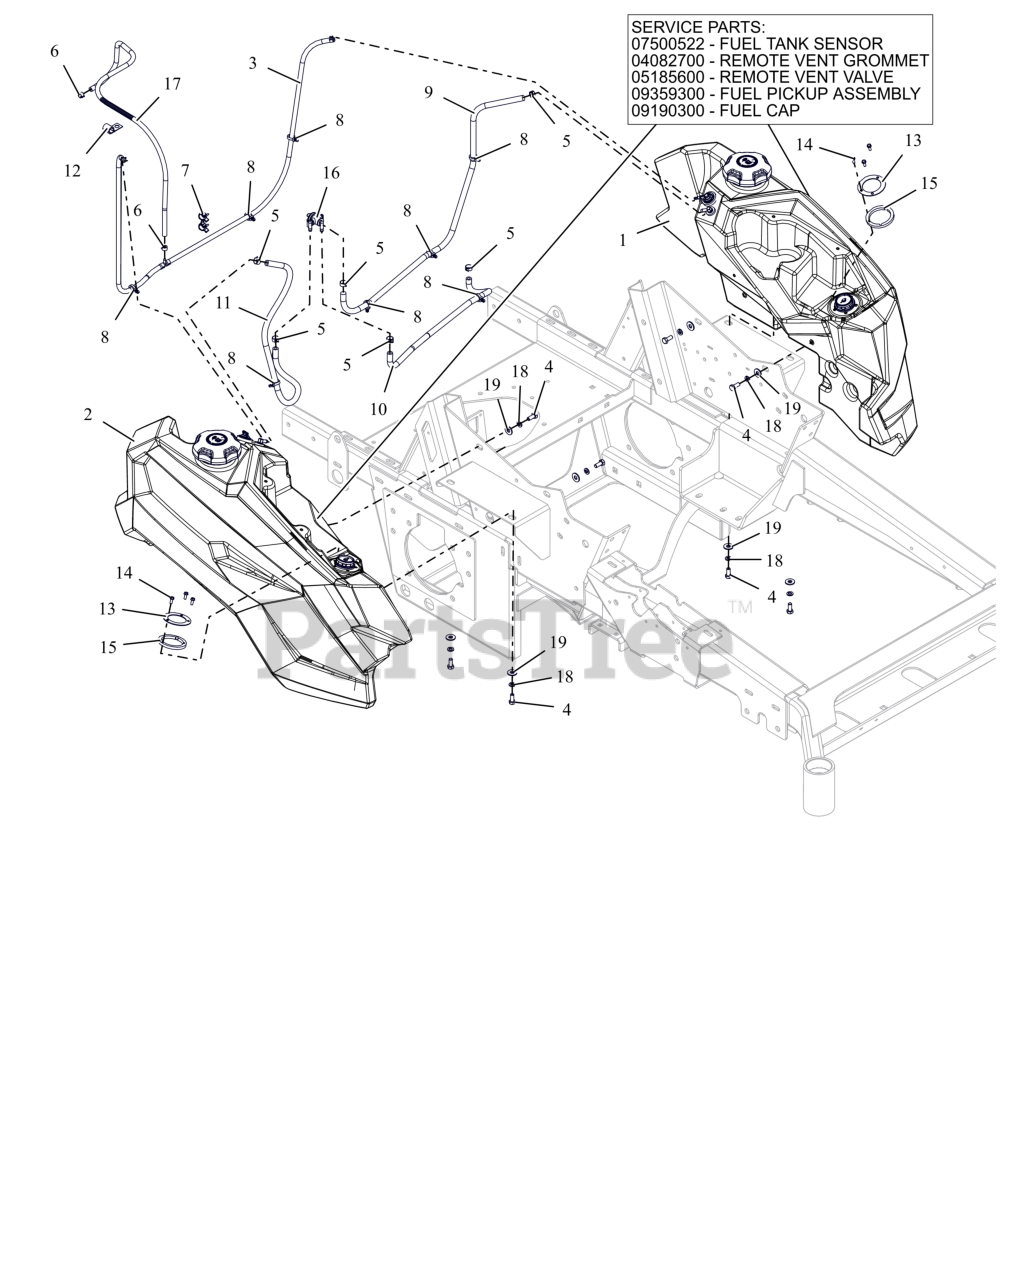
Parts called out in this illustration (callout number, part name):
1	ASM- PT300-500 LH FUEL TANK
1	GAUGE- REMOTE SEALED FUEL
1	GROMMET, REMOTE VENT NITRILE
1	VALVE, COMBINATION VENT 3/16
1	FUEL PICKUP ASSEMBLY
1	CAP, FUEL - 3.50 RATCHET INLET VENT
2	ASM- PT300-500 RH FUEL TANK
3	ASM- PT300/500/600 VENT LINE
4	BLT,HEX .31-18X.75 G5 ZCC
5	CLAMP, FUEL LINE
6	CLAMP-HOSE, SPRING .188
7	CLIP-360DEG SWIVEL.500DIA HOSE
8	CLIP- PUSH-IN X-MAS TREE CABLE
9	1 INCH OF HOSE, .25 LOW-PERM BULK GAS
10	1 INCH OF HOSE, .25 LOW-PERM BULK GAS
11	1 INCH OF HOSE, .25 LOW-PERM BULK GAS
13	RETAINER, FUEL GAUGE (BLACK)
14	SCR-MCH 10-24X.50 HWHSTAINLESS
15	SPCR, FUEL GAUGE RETAINER (BLACK)
16	VALVE, FUEL - WITH MAGNET
17	HOSE, .188 30R7 BULK
18	WSHR,LK-REG .312X.078 ZCC
19	WSHR,FLT .375X.875X.083 ZCC
